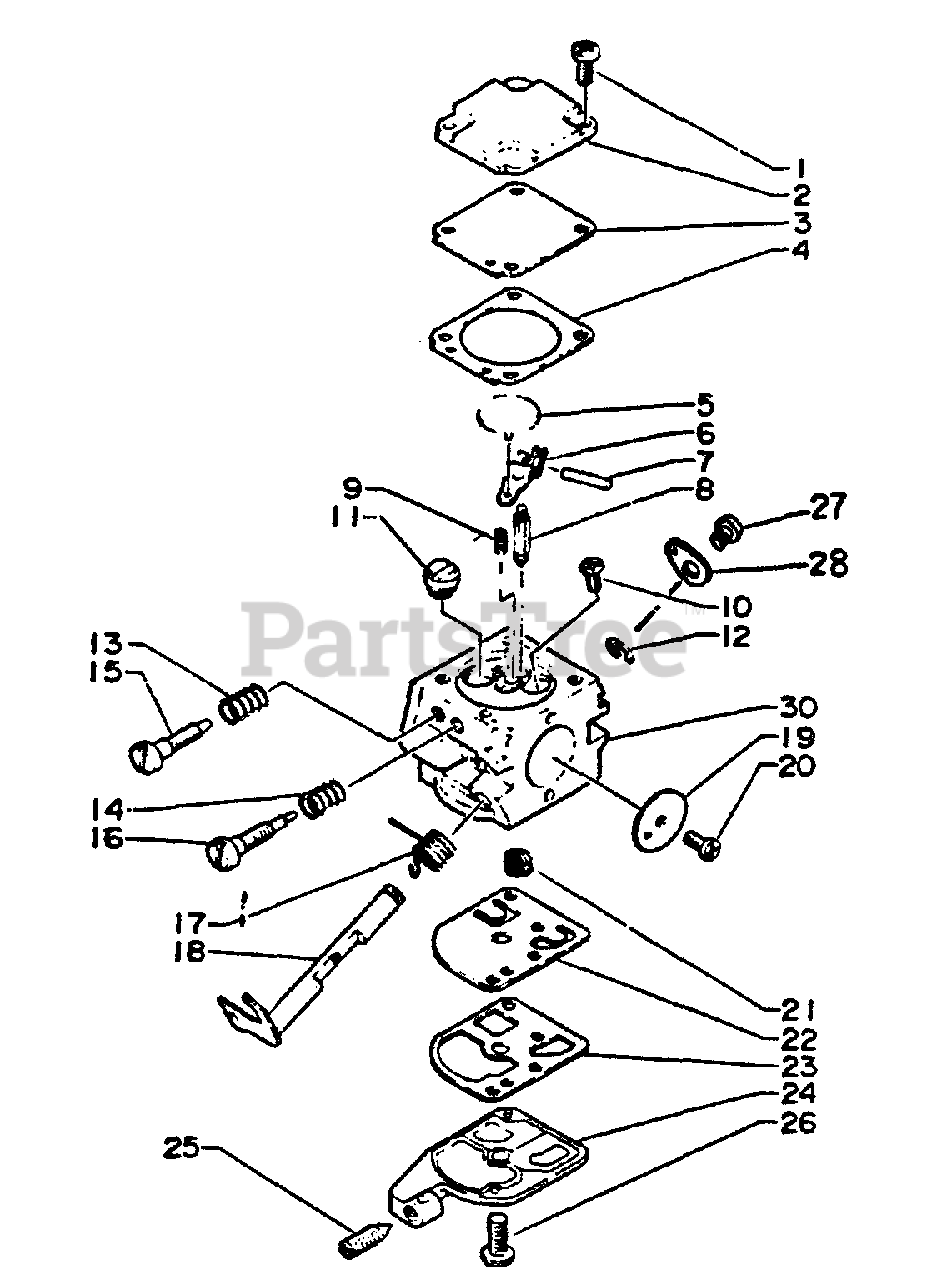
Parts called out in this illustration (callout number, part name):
1	SCREW
2	COVER, METERING
3	DIAPHRAGM
4	GASKET, METERING
5	PLUG, WELCH
6	LEVER, METERING
7	PIN, METERING LEVER
8	NEEDLE, INLET
9	SPRING, METERING LEVER
10	SCREW, METERING LEVER PIN
11	NOZZLE, CHECK VALVE
12	RING, RETAINING
15	NEEDLE - HIGH SPEED
16	NEEDLE - LOW SPEED
17	SPRING, RETURN
18	SHAFT, THROTTLE
19	VALVE, THROTTLE
20	SCREW
21	STRAINER
22	DIAPHRAGM, PURGE
23	GASKET, PURGE
24	BASE, PURGE
25	SCREW, IDLE ADJUST
26	SCREW, PUMP COVER
28	LEVER, THROTTLE
30	BODY, CARBURETOR
